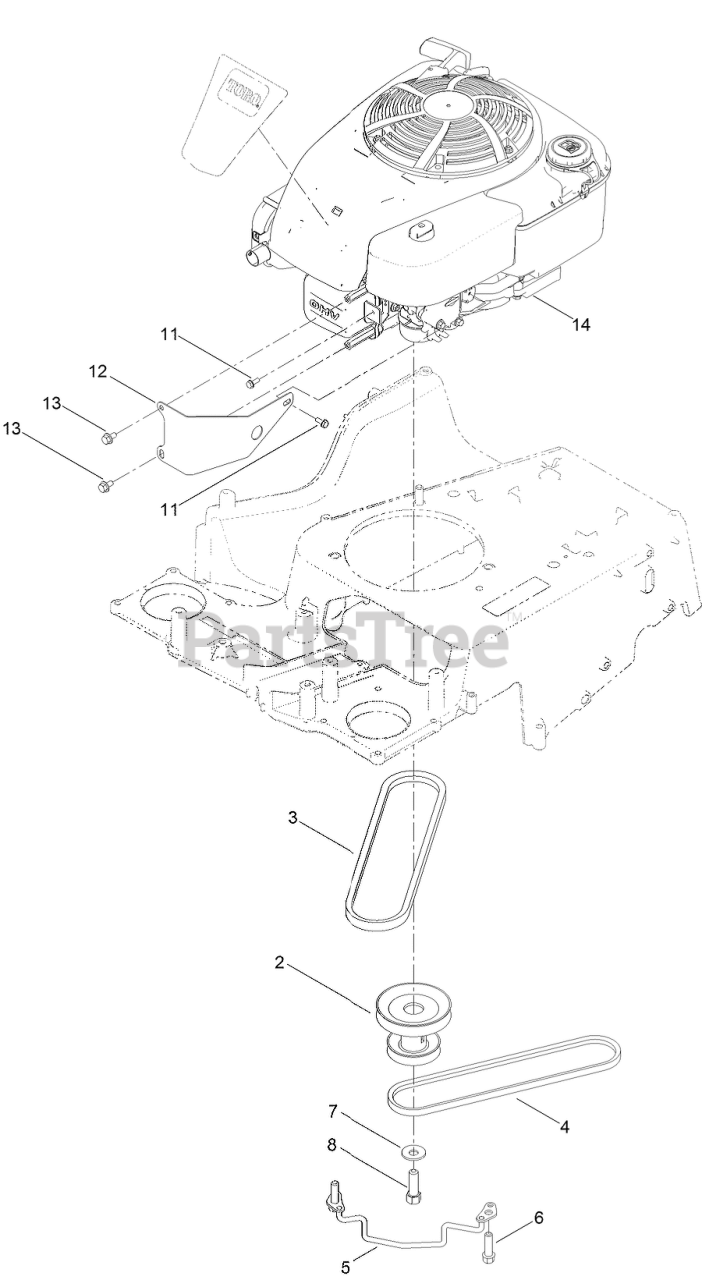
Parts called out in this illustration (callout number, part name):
2	PULLEY-ENGINE
3	V-BELT
4	V-BELT, TRACTION
6	SCREW-TAPTITE
7	WASHER-BELLEVILLE
8	SCREW-HH
11	SCREW-TAPTITE
12	GUARD-ENGINE
13	SCREW-HHF
